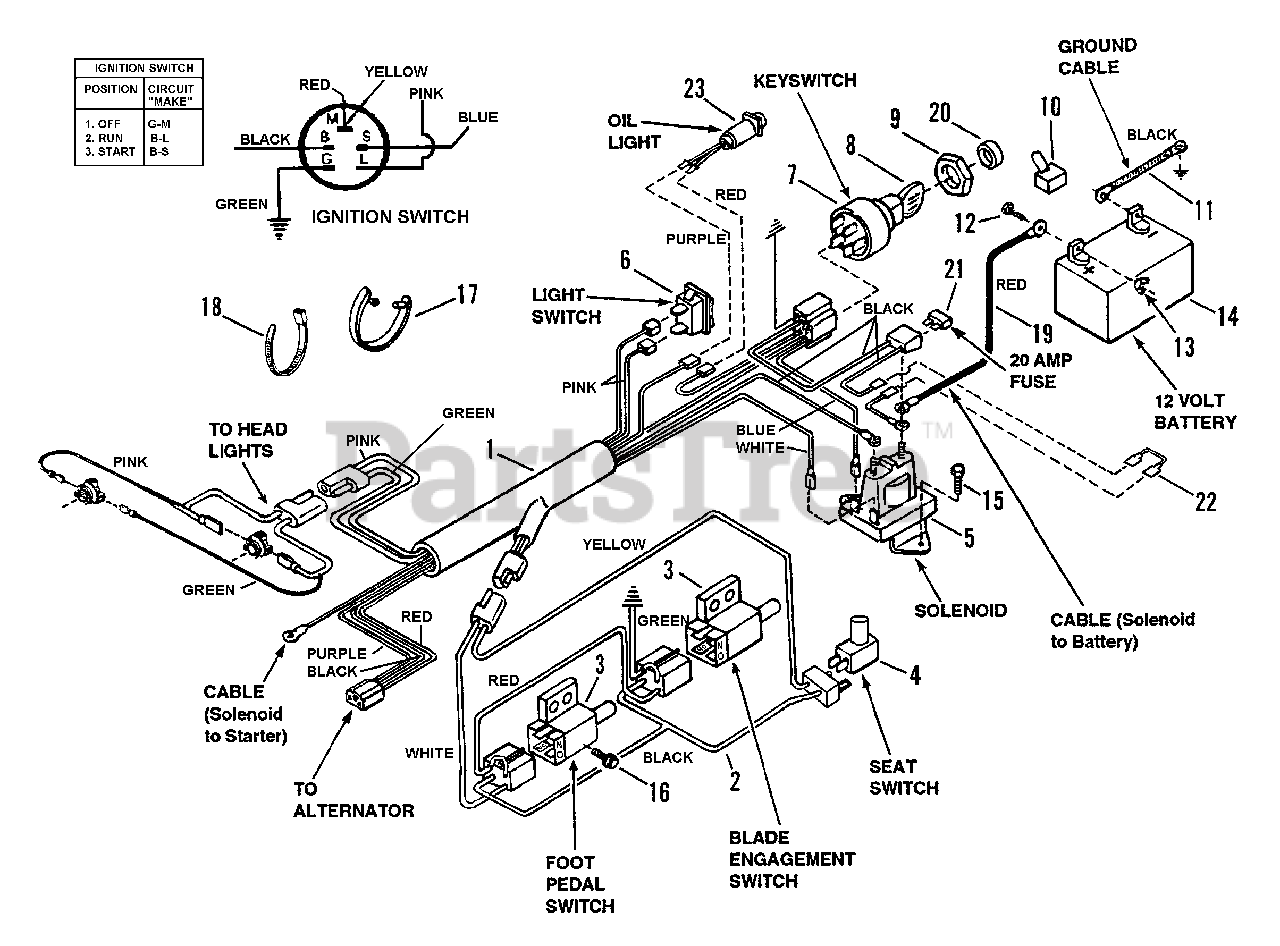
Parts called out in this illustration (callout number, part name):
1	HARNESS, Wiring (Kohler Engine)
2	HARNESS, Interlock
3	SWITCH, Clutch & PTO NC/NO
4	SWITCH, Seat NC
5	SOLENOID
6	SWITCH, Light
7	SWITCH, Key
8	KEY, Switch (With Cover)
9	NUT, 5/8-32 Hex
10	COVER, Positive Terminal
11	CABLE, Negative 15"
12	BOLT, 1/4-20 x 3/4" Carriage
13	WING-NUT, 1/4-20
14	KIT, Battery
15	SCREW, 1/4-20 x 1/2" Self-Tapping
16	SCREW, #10-24 x 1/2" Hex Washer Self-Tap (Torx)
17	TIE, Wire
18	TIE, Cable 7"
19	CABLE, Positive 11"
20	BEZEL
21	FUSE, 20 Amp
22	CONNECTOR 4"
23	OIL LIGHT
